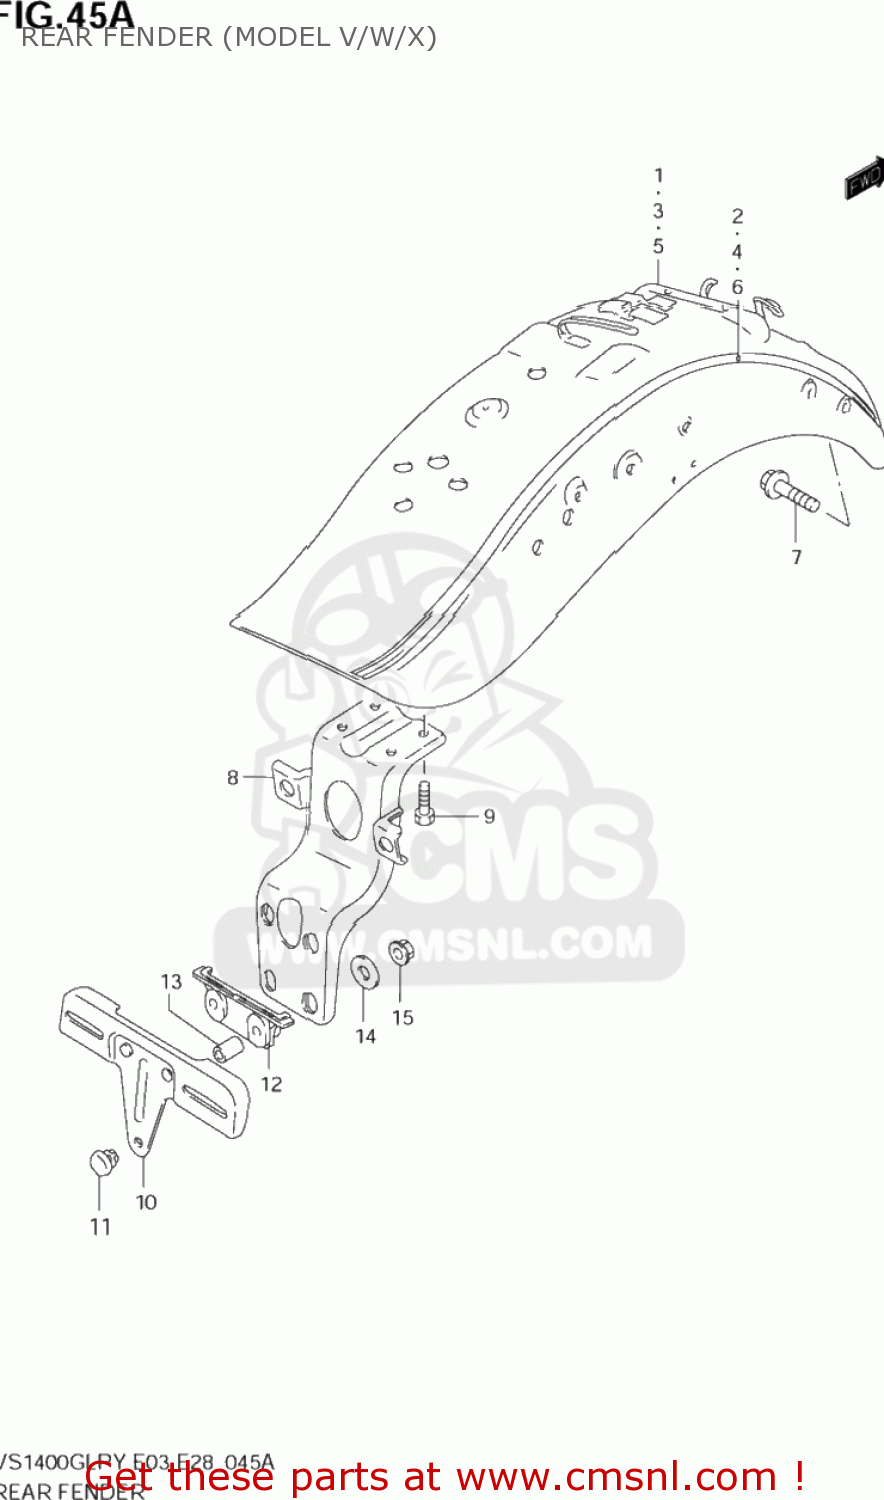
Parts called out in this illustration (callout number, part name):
1	FENDER ASSEMBLY,REAR
2	TAPE SET,RR FENDER
3	FENDER, REAR
4	TAPE SET,RR FENDER
5	FENDER ASSY,RR
6	TAPE SET,REAR FENDER S
7	BOLT
8	BRACKET,RR COMBINATION LAMP
9	BOLT
10	PLATE,REAR LICENSE
11	CUSHION
12	CUSHION,RR LICENSE PLATE
13	SPACER(5.5X8X14.3)
14	WASHER(5.5X20X1.2)
15	NUT
